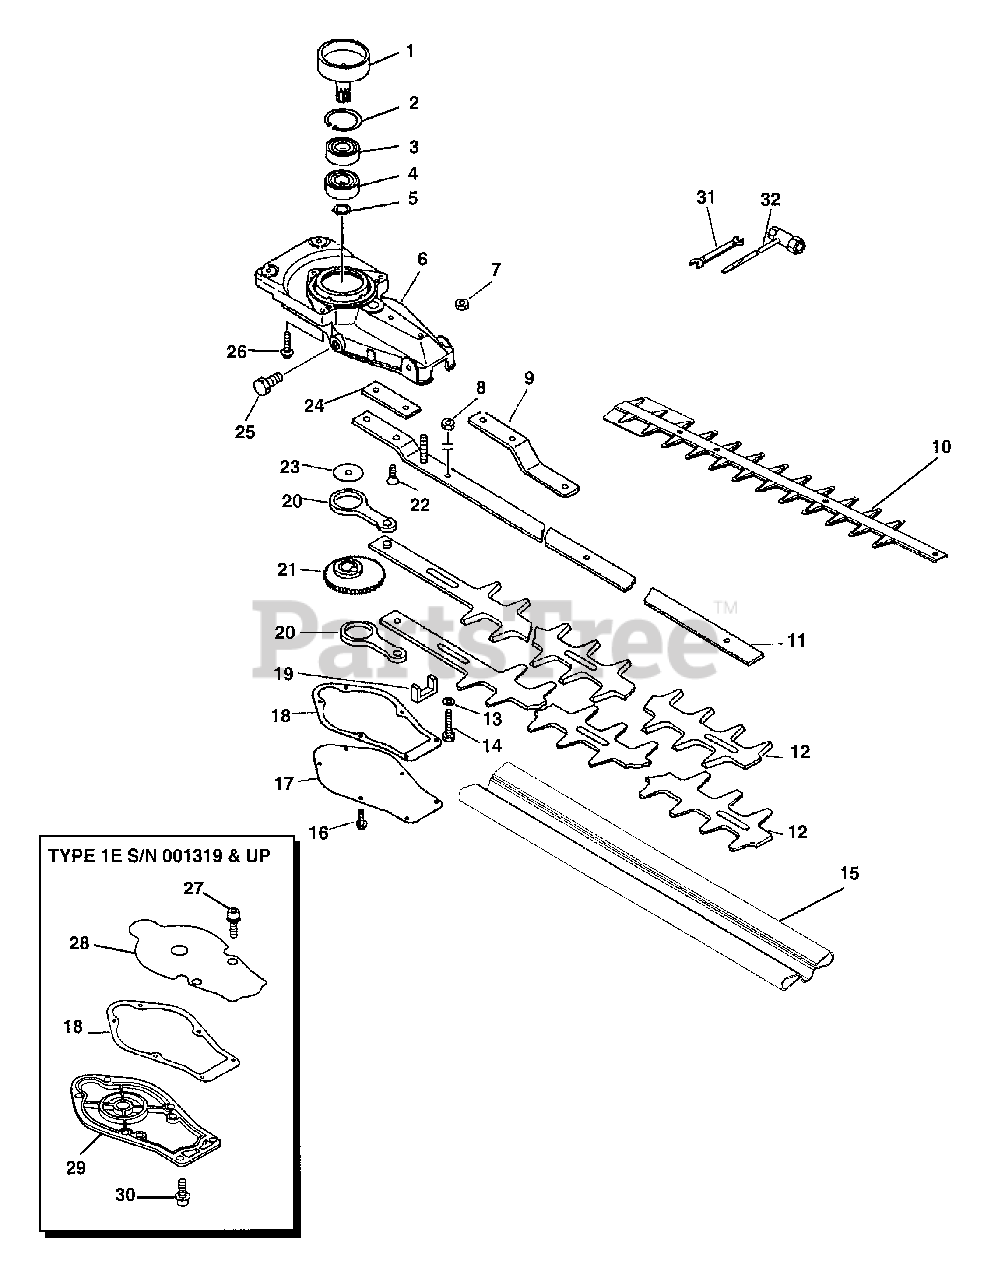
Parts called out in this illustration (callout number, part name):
1	DRUM, CLUTCH
2	RING, RETAINING - 35
3	BEARING, BALL - 6202
4	BEARING, BALL - 6202
5	RING, RETAINING - 14
6	CASE, GEAR
6	CASE, GEAR - UPPER
7	LOCKNUT - 6
8	LOCKNUT - 6
9	PLATE, ANGLE
10	SUPPORT, BLADE
11	SUPPORT, BLADE
12	BLADE, TRIMMER
13	WASHER - 6
14	BOLT - 6X18
14	SCREW
15	COVER, BLADE
16	SCREW - 4X10
17	LID, GEAR CASE
18	GASKET, GEAR CASE
19	SEAL, FELT
20	ROD, CONNECTING
21	GEAR - DRIVE
22	SCREW - 6X25
25	BOLT - 8X8
26	SCREW - 5X25
27	SCREW - 5X12
28	LID, GEAR CASE
29	LID, GEAR CASE - LOWER
30	SCREW - 4X12
31	T-WRENCH - 13X19mm
32	SPANNER - 8X10mm
